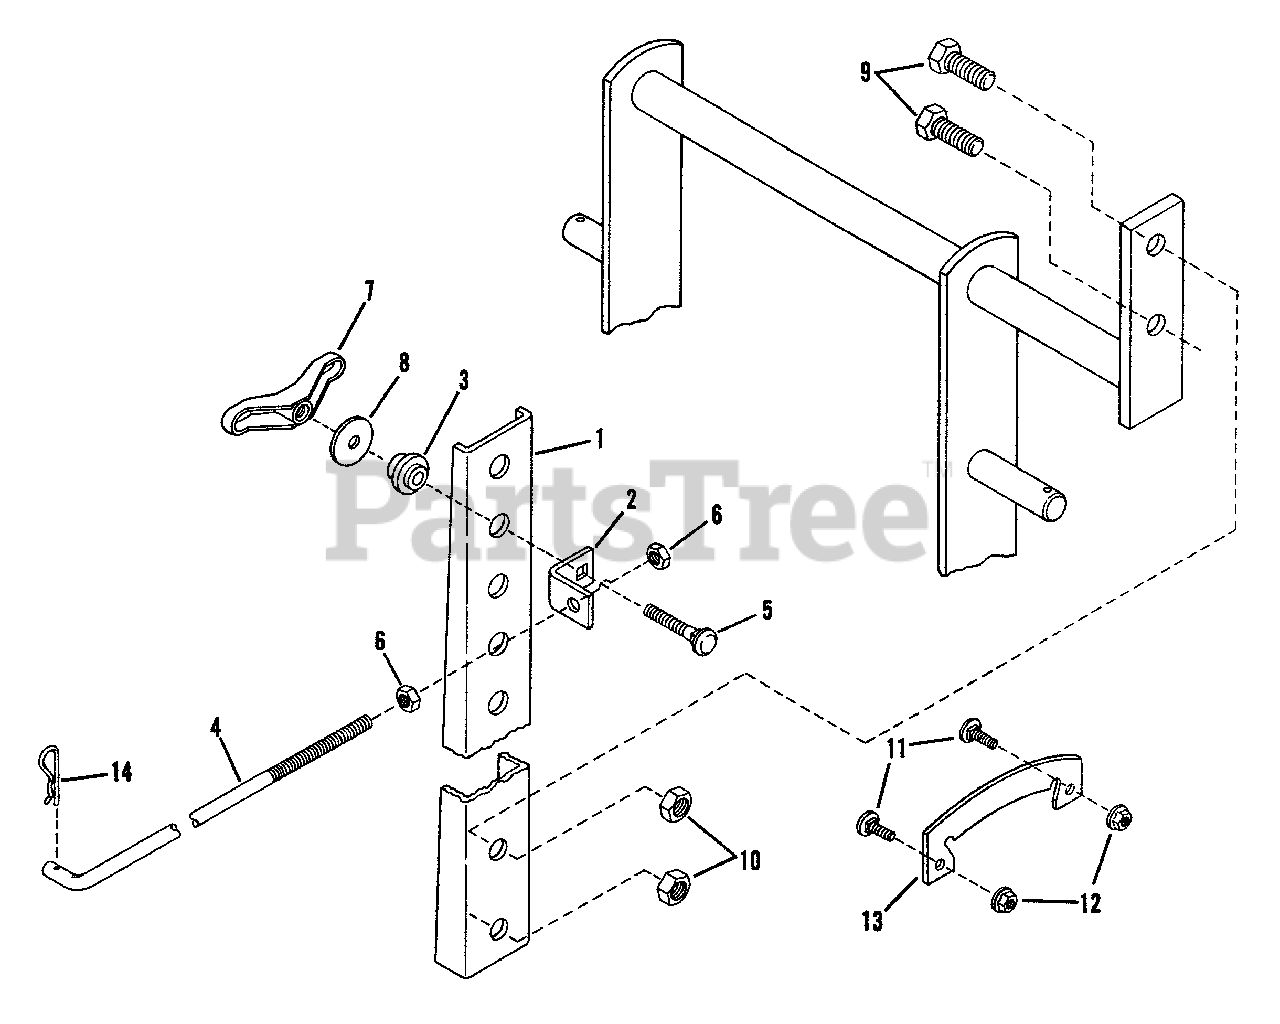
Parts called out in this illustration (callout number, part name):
1	ARM, Lift
2	SWIVEL, Lift Rod
3	SPACER
4	ROD, Lift
5	BOLT, 5/16-18x1-3/8" Carriage
6	NUT, 3/8-16 Hex
7	NUT, 5/16-18 Wing
8	WASHER, 5/16" x 1-1/4" x 3/32" Flat
9	SCREW, 1/2-13x1" Hex Head Cap
10	NUT, 1/2-13 Hex
11	BOLT, 1/4-20x5/8" Flat Head Carriage
12	NUT, 1/4-20 Hex Flange Lock
13	PLATE, Quadrant
14	HAIRPIN
